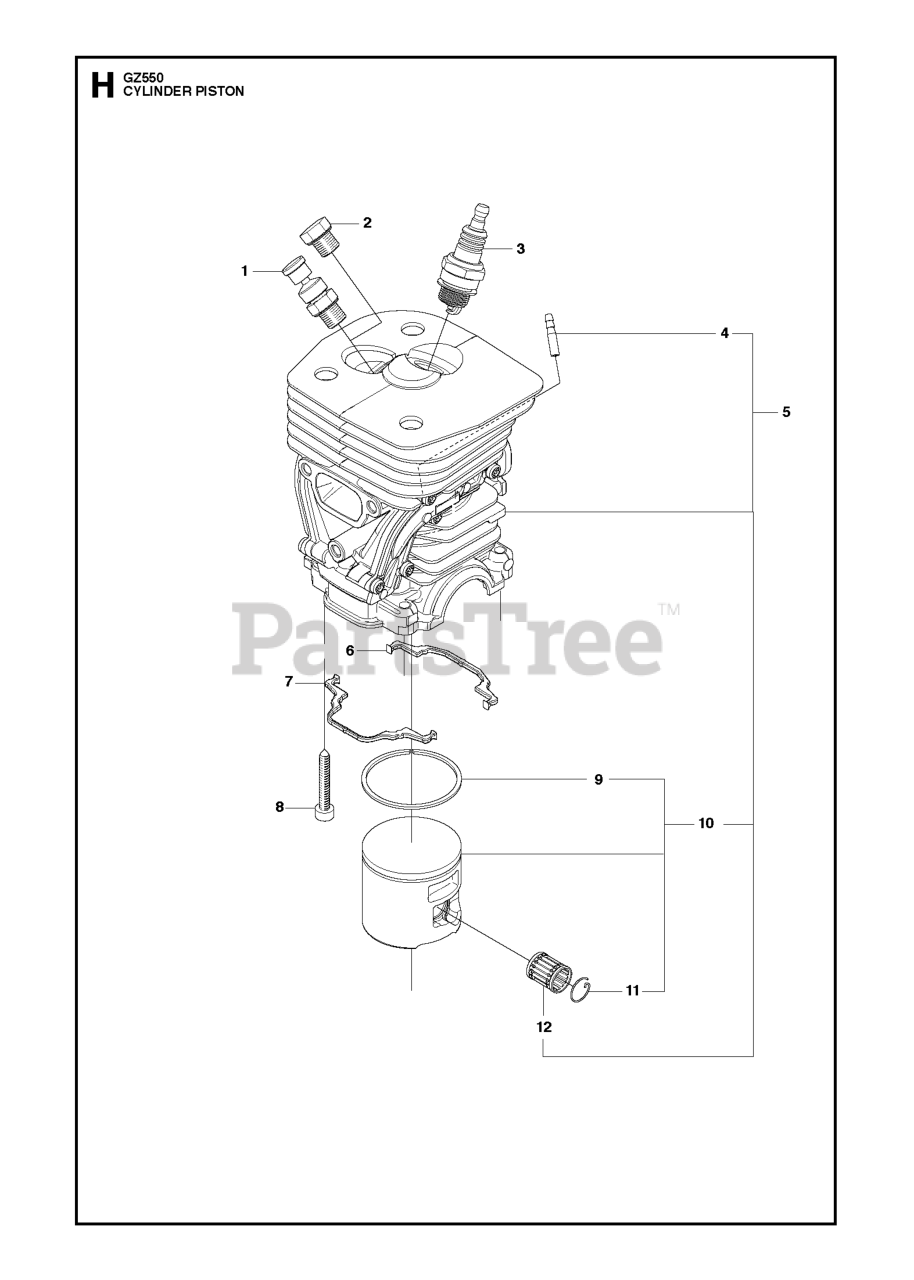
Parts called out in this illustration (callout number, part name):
2	CYLINDER PLUG
3	HQT-1 HH SPARK PLUG - BPMR7A
5	CYLINDER
9	PISTON RING
10	PISTON ASSY
11	WRIST PIN CLIP
12	SUPPORT BUSHING
